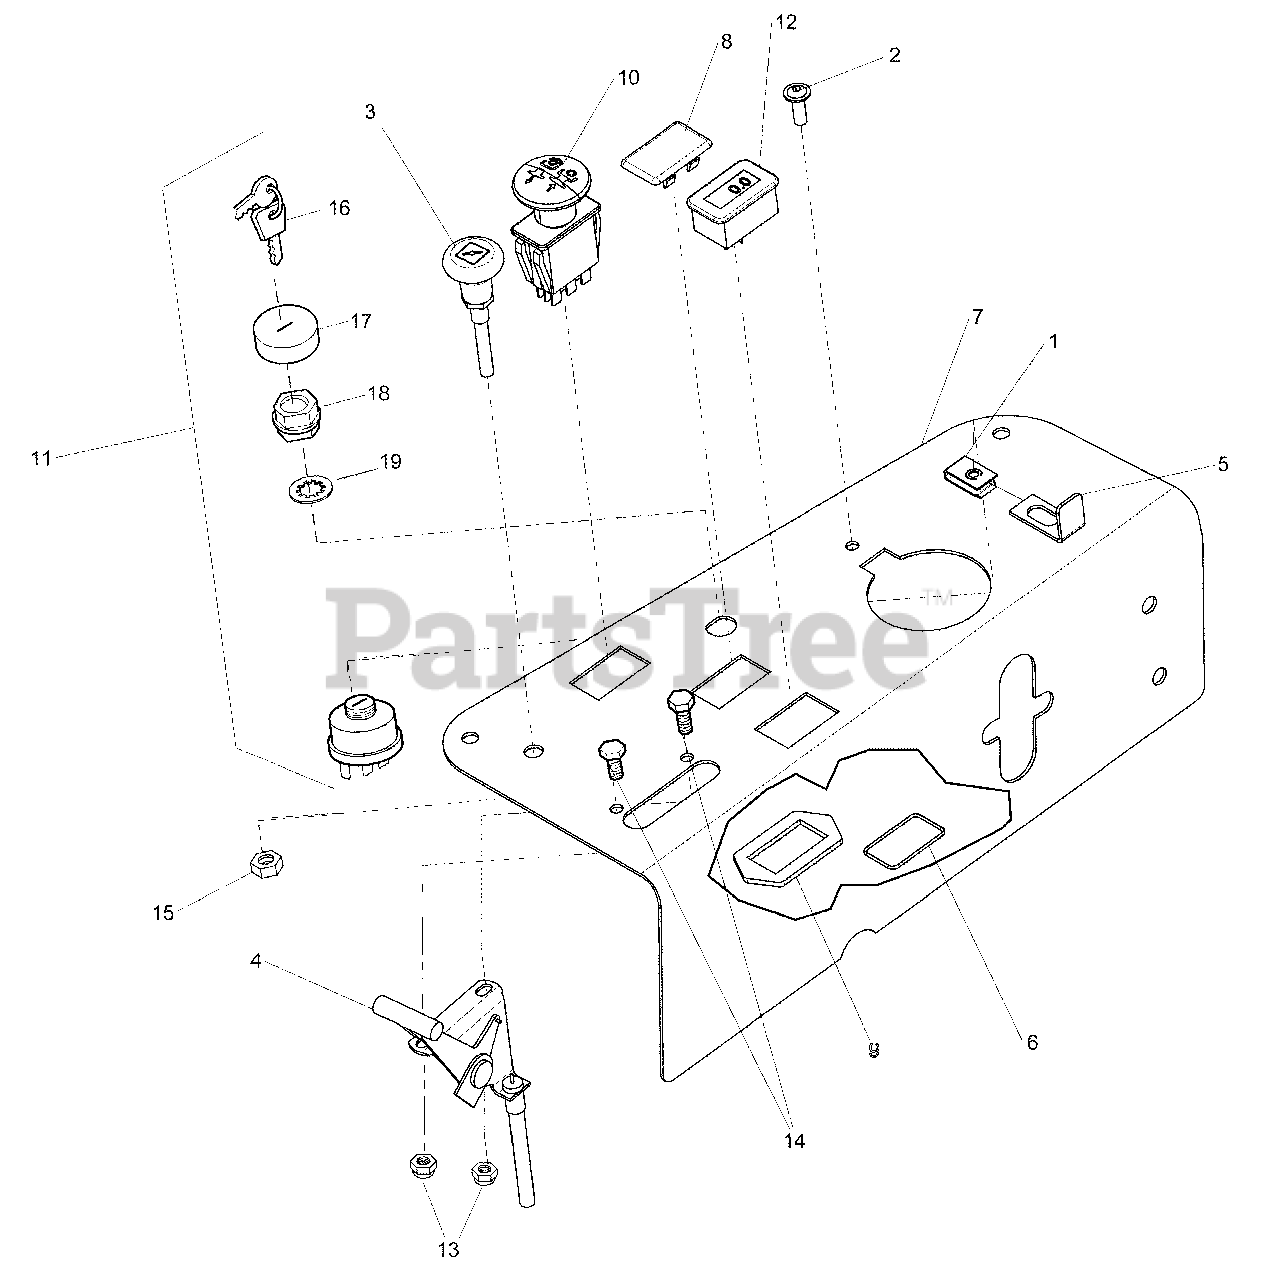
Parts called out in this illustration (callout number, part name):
1	BODY CLIP, 1/4-20 X .500 DEEP
2	SCREW, ALLEN HEAD, 1/4-20 X 3/4"
3	CHOKE CABLE
4	CABLE THROTTLE, 48"
5	BRACKET, LOCK
6	O-RING, 7/8" ID X 1/16" W
7	PLATE, CONTROL TANK COVER
8	HOLE, PLUG DASH
9	RING, SWITCH RETAINER, PTO
10	SWITCH, BLADE ENGAGEMENT
11	SWITCH ASMY-IGNITION INDAK NO KEYS
12	HOUR METER-DIGITAL
13	NUT, Hex Nylon Lock, 1/4-20
14	BOLT, 1/4-20 x 3/4
15	NUT, 3/8-24 HEX
16	KEYS. BLISTER PK KIDS+MWRS DON'T MIX, USA Models Only
17	COVER, SWITCH
18	NUT-HEX FLANGE, 5/8-32 IGN SW DIE CAST
19	LOCKWASHER-INTERNAL TOOTH, .625 THIN BLK
